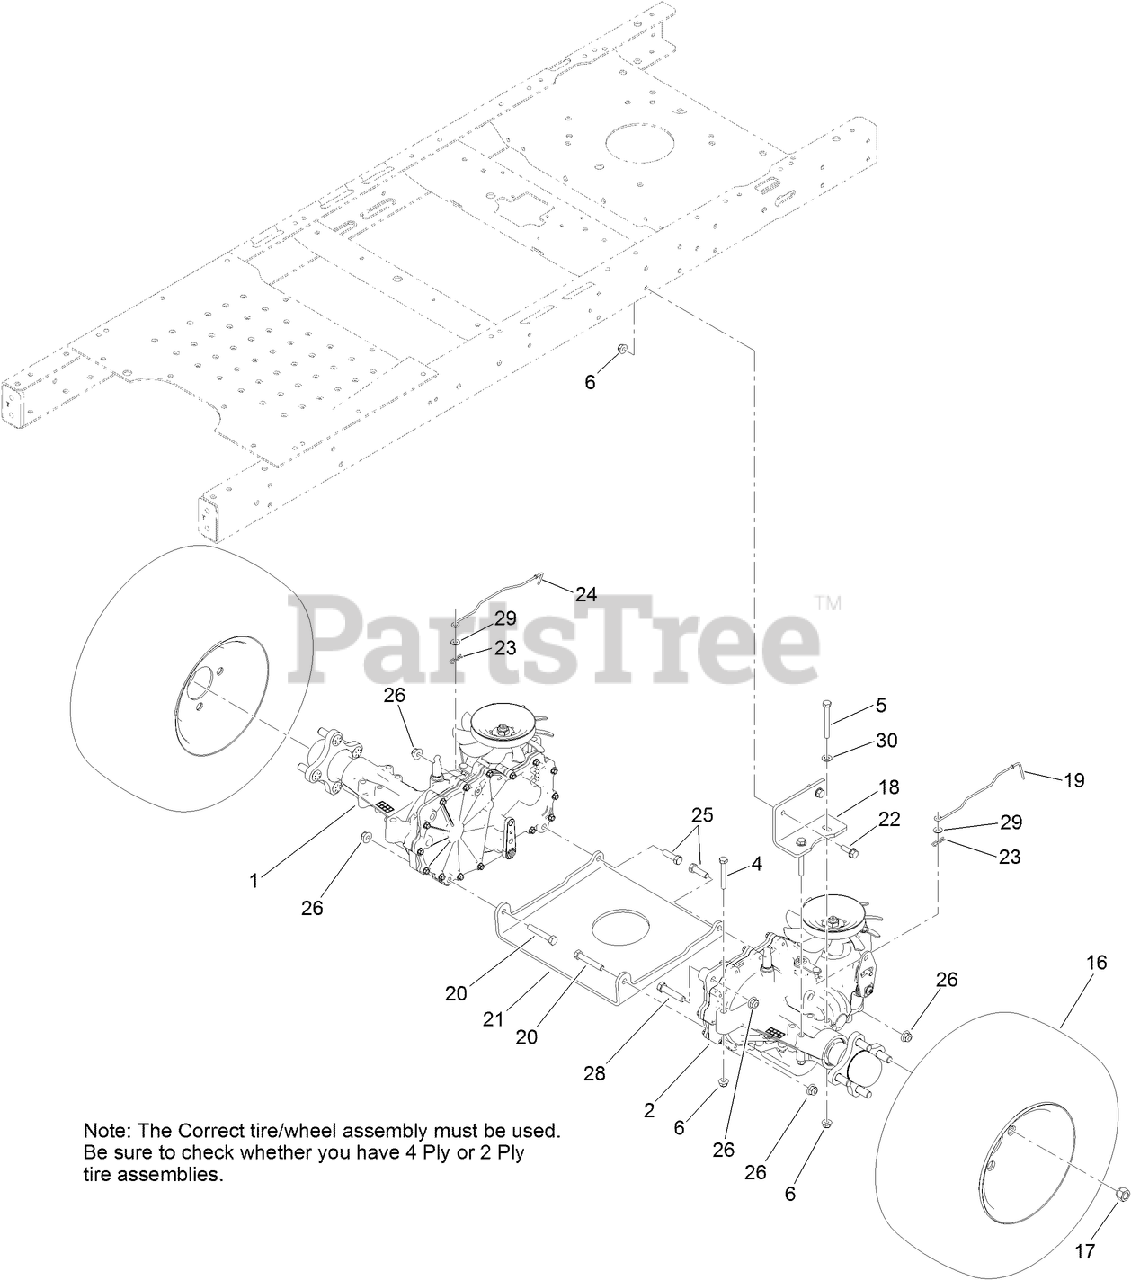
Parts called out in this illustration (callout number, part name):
1	RH HYDRO TRANSMISSION ASM
2	LH HYDRO TRANSMISSION ASM
4	SCREW-HH
5	SCREW-HH
6	NUT-HF, NI
16	4 PLY WHEEL AND TIRE ASM
16	2 PLY TIRE AND WHEEL ASM
17	NUT-LUG
18	MOUNT-HYDRO
19	ROD-BYPASS, LH
20	SCREW-HH
21	PLATE-CROSS, HYDRO
22	SCREW-HHF
24	ROD-BYPASS, RH
25	SCREW-HH
26	NUT-HF, NI
28	SCREW-HH
29	WASHER
30	WASHER-PLAIN
